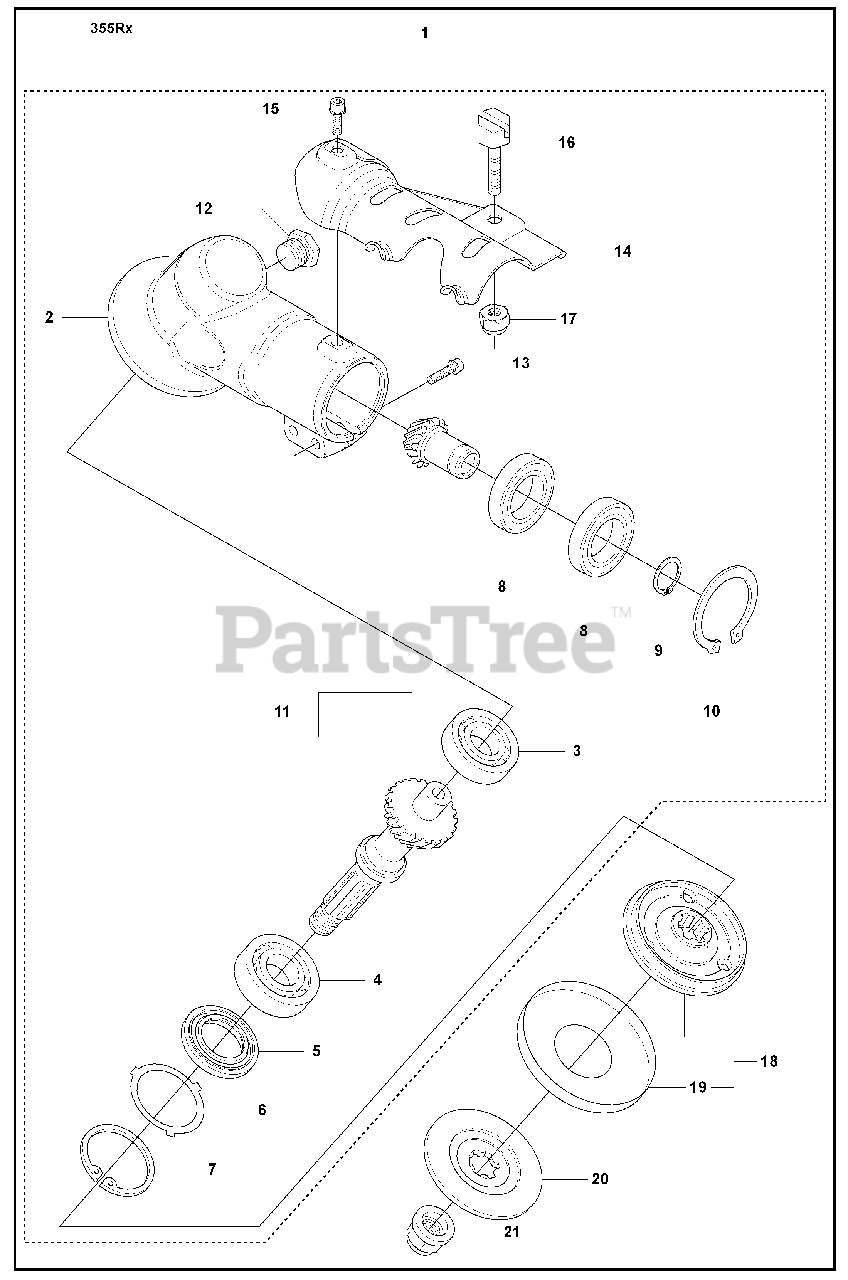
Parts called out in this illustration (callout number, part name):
2	GEAR HOUSING
3	BALL BEARING
4	BALL BEARING
7	RETAINING RING SGH 35
8	BALL BEARING
9	RETAINING RING SGA 15
10	RETAINING RING
11	BEVEL GEAR
14	ATTACHMENT PLATE
17	LOCKNUT M6
19	GRASS SEALING
20	SUPPORT FLANGE
21	BLADE NUT
